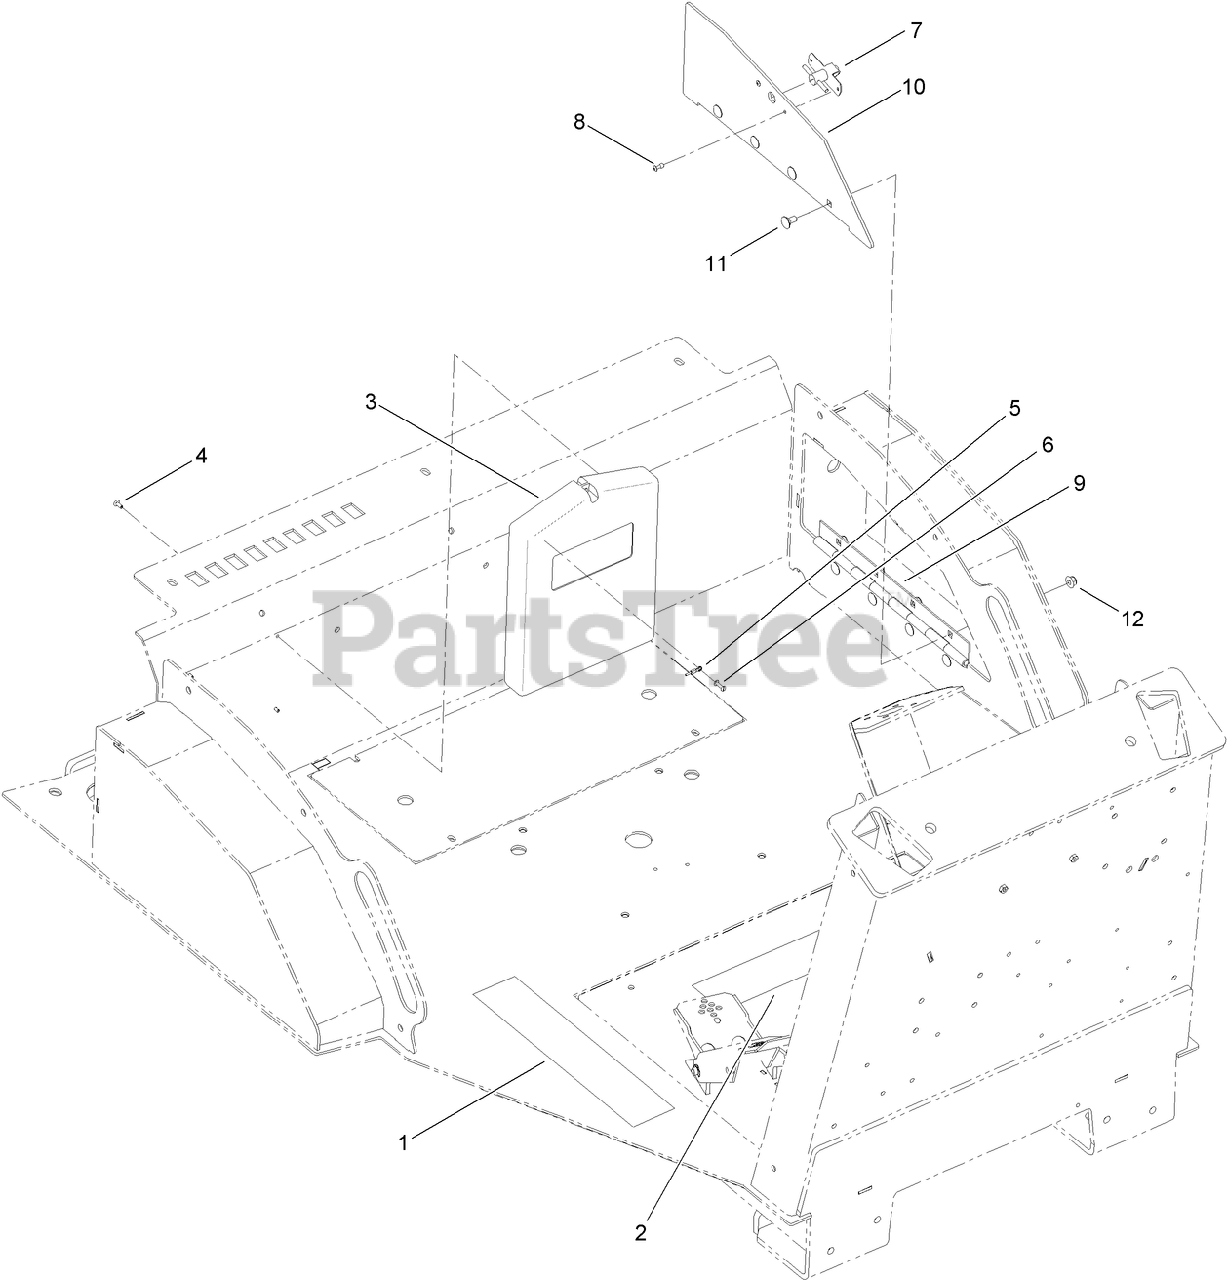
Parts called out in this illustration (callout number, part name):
1	TAPE-ANTI SKID, UPPER STEP
2	TAPE-ANTI SKID, LOWER STEP
3	HOLDER-MANUAL, OPERATOR
4	RIVET-BLIND
5	LANYARD
6	POST-MANUAL
8	RIVET-POP
10	PLATE-DOOR
11	SCREW-CARR
12	NUT-HF, NI
